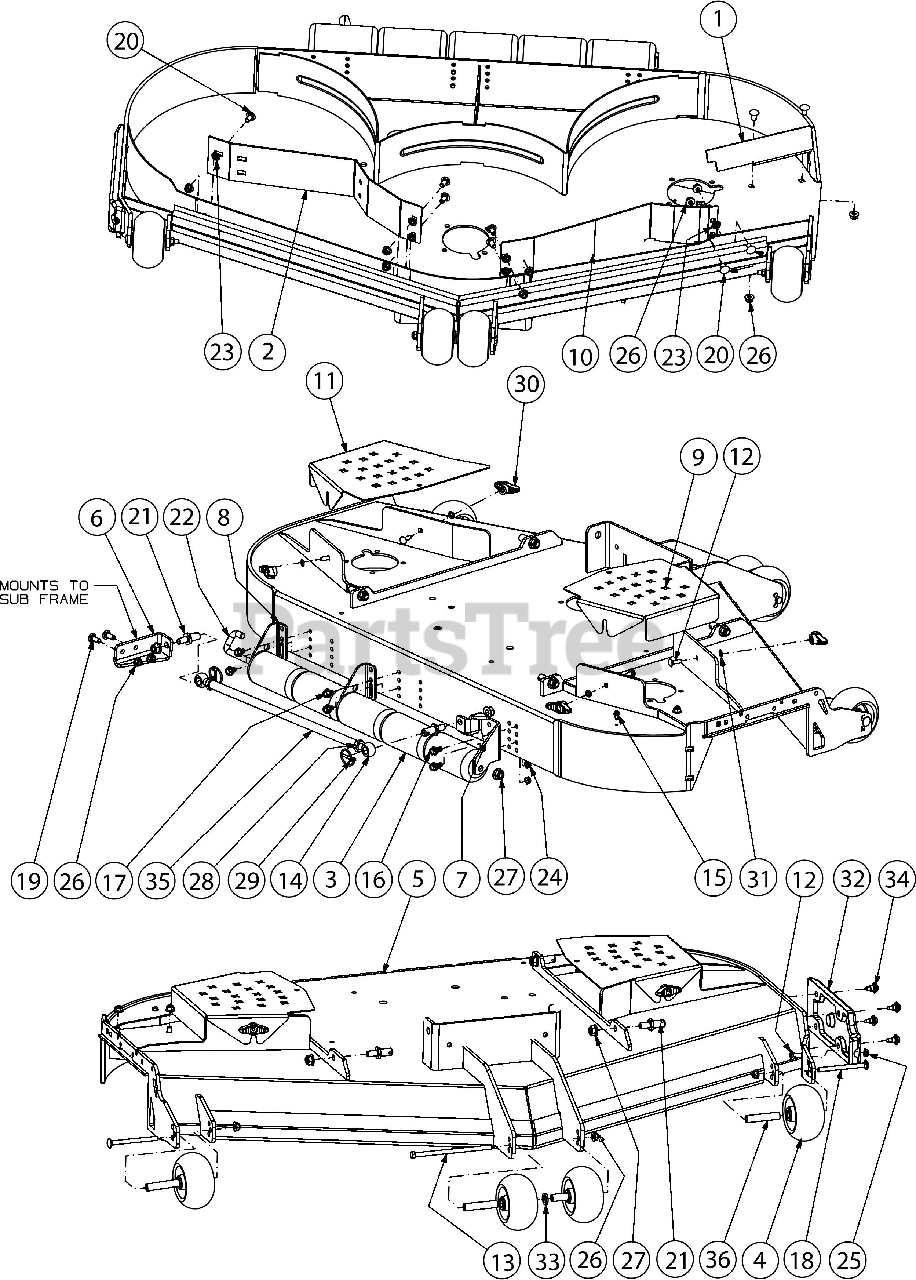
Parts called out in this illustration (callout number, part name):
3	ROLLER ASSEMBLY
4	WHEEL ASSEMBLY 5"
5	60" FAB DECK SHELL ASSEMBLY
6	STABILIZER MOUNTING BRACKET
7	REAR ROLLER/STABILIZER BRACKET
8	REAR MOUNT BRACKET
9	DECK BELT COVER
10	DECK BAFFLE
12	CARRIAGE BOLT 5/16-18 x 1.00
13	SCREW 3/8-16 x 7.25 GR5
14	BOLT 5/8-16 x 2.63
15	SCREW 1/4-20 X.500
16	SCREW 3/8-16 x 3/4
17	SCREW 3/8-16 x .500
18	CARRIAGE BOLT 3/8-16 x 4.25 GR5
19	CARRIAGE BOLT 3/8-16 x 1.00 GR5
20	CARRIAGE BOLT 3/8-16 x .75
22	REAR ROLLER PIN
24	JAM LOCK NUT
25	FLANGE LOCK NUT 5/16-18
28	HEX NUT
30	WING KNOB 5/16-18
32	DECK SKID PLATE (LH)
33	FLAT WASHER .632X1.00X.16
34	SHOULDER SCREW .43X.29X5/16-18 TT
36	WHEEL SPACER .38ID x 3.04LG
